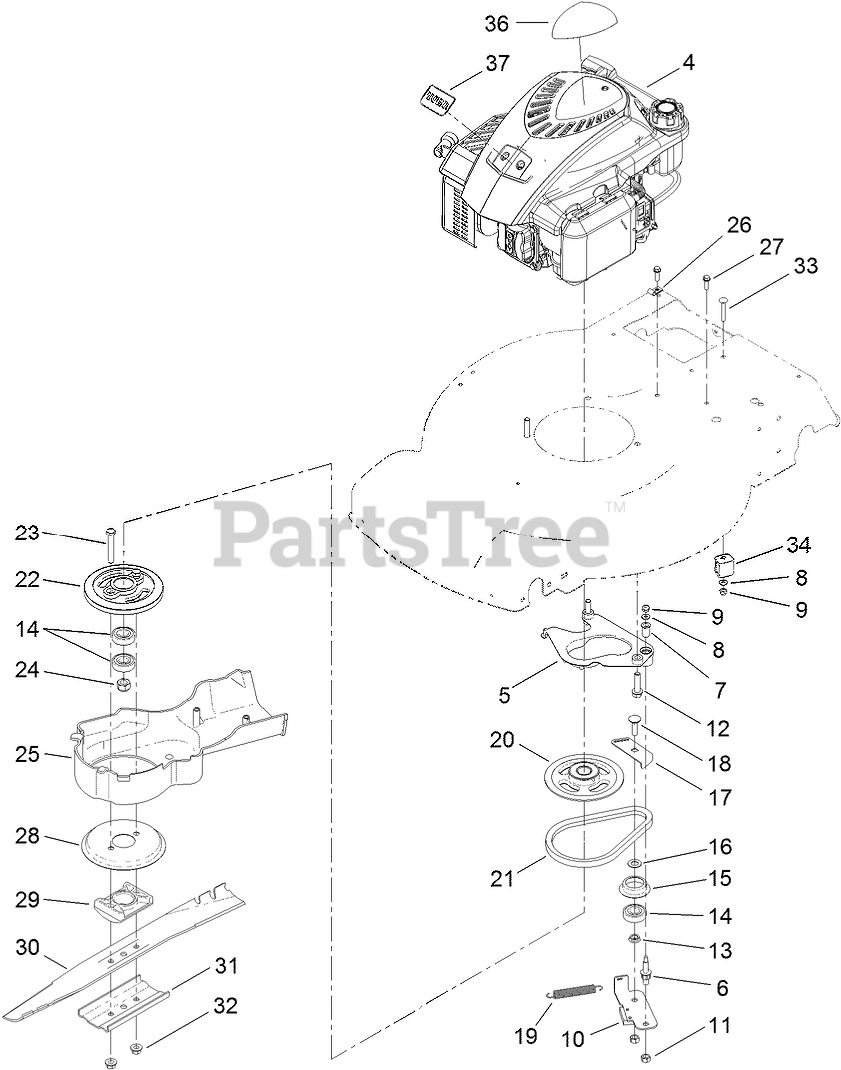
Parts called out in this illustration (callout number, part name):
4	ENGINE-1P65FA
5	PLATE-ANCHOR
6	BOLT-SHOULDER
7	BUSHING
8	WASHER-FLAT
9	NUT-LOCK, NI
10	BRAKE ARM ASM
12	SCREW-HWH
13	SPACER-BEARING
14	BEARING-BALL
15	RETAINER-BELT
16	WASHER-PLAIN
17	PLATE-GUIDE
18	BOLT-CARR
19	SPRING-TENSION, BRAKE
20	PULLEY
21	BELT
22	DRUM
23	SCREW-HH
24	NUT-HEX
26	CLIP-CLOSED, INSULATED
27	SCREW-HWH
28	DISC
29	SUPPORT-BLADE
30	BLADE-22 INCH
31	SUPPORT-BLADE
32	NUT-LOCK
33	SCREW-CARR
34	ANCHOR-CABLE
36	DECAL-SHROUD
